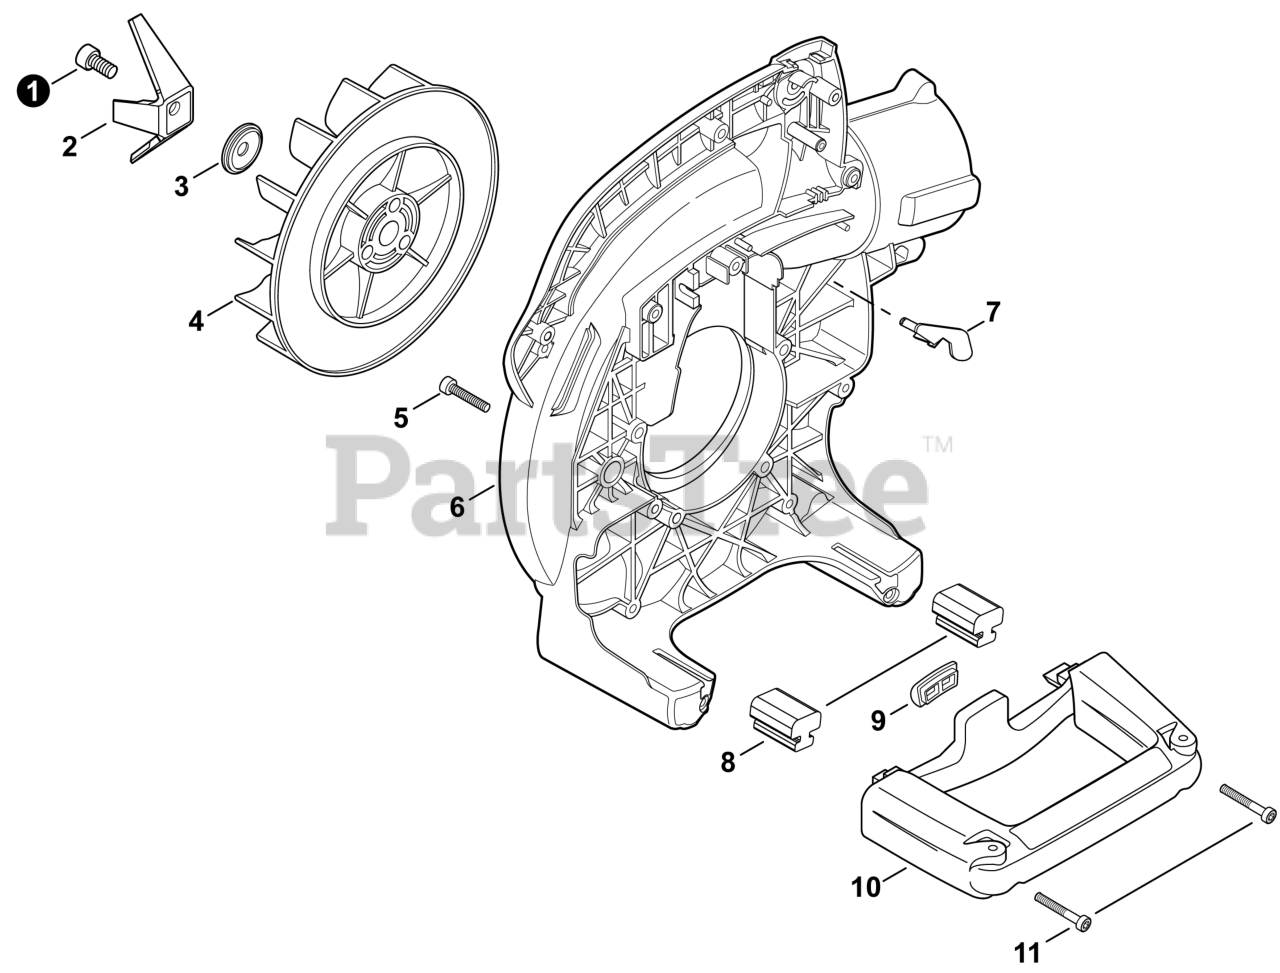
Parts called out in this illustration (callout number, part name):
1	BOLT 8x15
2	CUTTER, SHREDDER
3	WASHER 8.2x31x0.8
5	BOLT, TORX 4x20
6	CASE, FAN
9	CUSHION
10	HANDLE, REAR
11	BOLT, TORX 5x25
